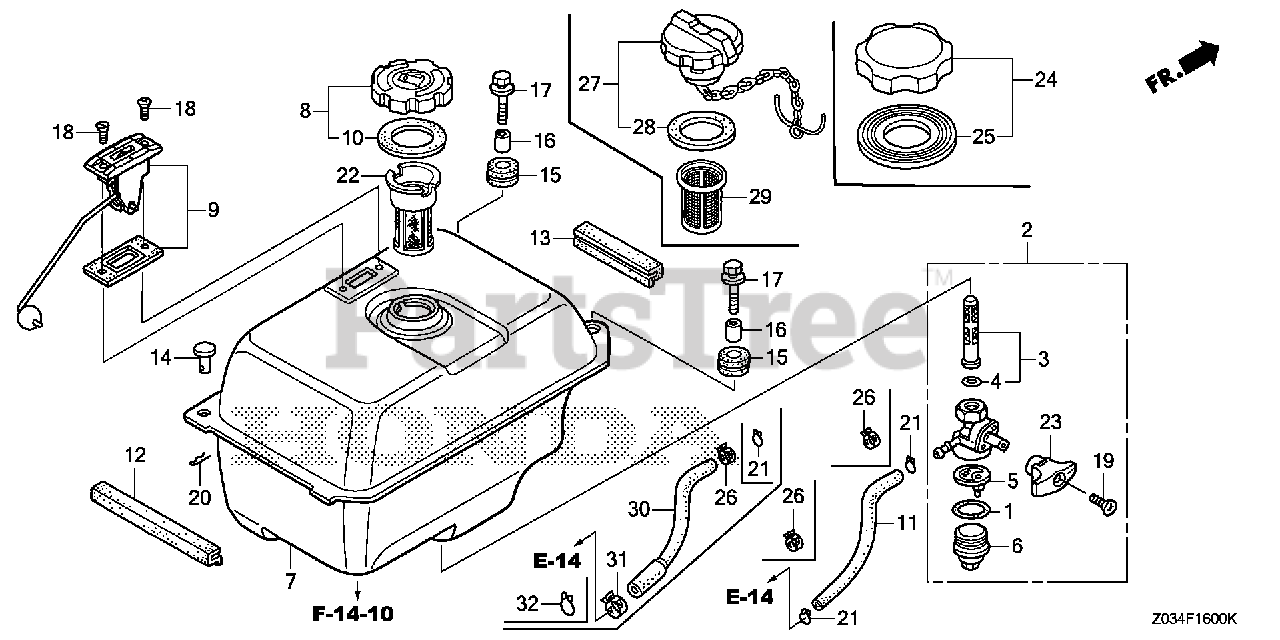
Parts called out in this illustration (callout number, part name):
1	GASKET, FUEL STRAINER CUP
2	PETCOCK ASSY.
3	SCREEN SET, FUEL STRAINER
4	O-RING (9.0X1.3)
5	FILTER, CUP
6	CUP, FUEL STRAINER
7	TANK, FUEL *R280* (POWER RED)
8	CAP, FUEL FILLER (BLACK)
9	METER ASSY., FUEL
10	GASKET, FUEL FILLER CAP (39X58X3)
11	TUBE, FUEL TANK
12	SEAL A, FUEL TANK MOUNTING
13	SEAL B, FUEL TANK MOUNTING
14	PIN, CLUTCH JOINT
15	RUBBER, CONTROL BOX
16	COLLAR, CONTROL BOX
17	BOLT-WASHER (6X20)
18	SCREW, FLAT (5X10)
19	SCREW, OVAL (4X18)
20	PIN, LOCK (6MM)
21	CLIP, TUBE (B8)
22	FILTER, FUEL
23	LEVER, PETCOCK
